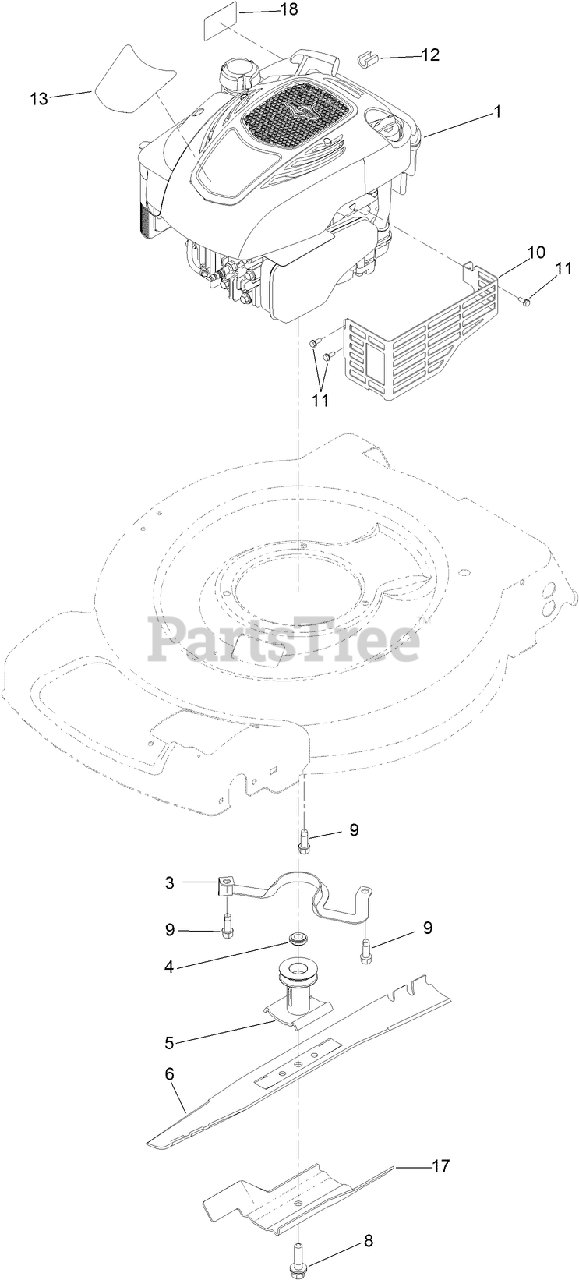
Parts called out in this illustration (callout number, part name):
3	GUIDE-BELT
4	SPACER-DRIVER
5	DRIVER-BLADE
8	BOLT-BLADE
9	SCREW-TAPTITE
10	SHIELD-MUFFLER
11	SCREW-TAPTITE
12	STOP-ROPE
13	DECAL-SHROUD
17	ACCELERATOR-BLADE
18	DECAL-FUEL LEVEL
